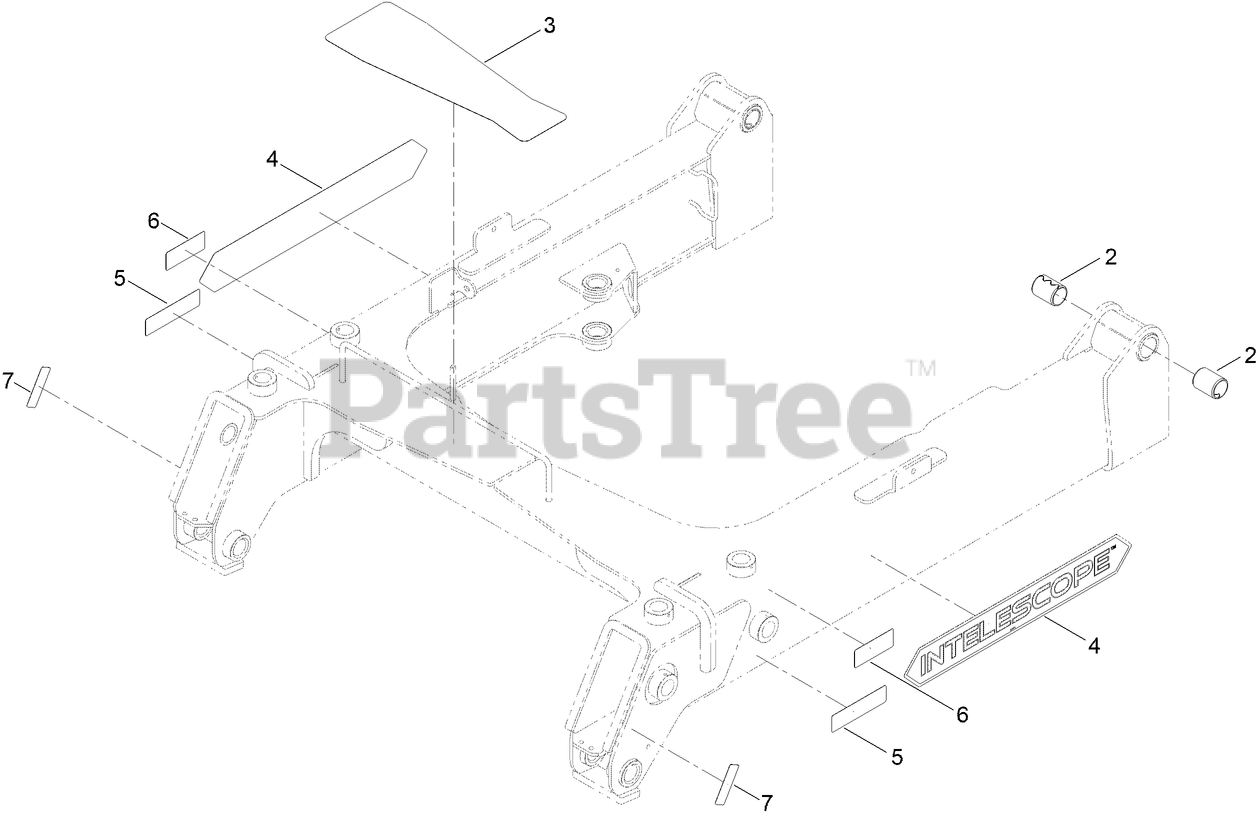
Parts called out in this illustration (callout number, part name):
2	BUSHING-SPRING
3	STRIP - WEAR
4	DECAL-INTELESCOPE
5	DECAL-WARNING, CRUSHING
6	DECAL-WARNING, BYSTANDERS
7	DECAL-WARNING, PINCH POINT
